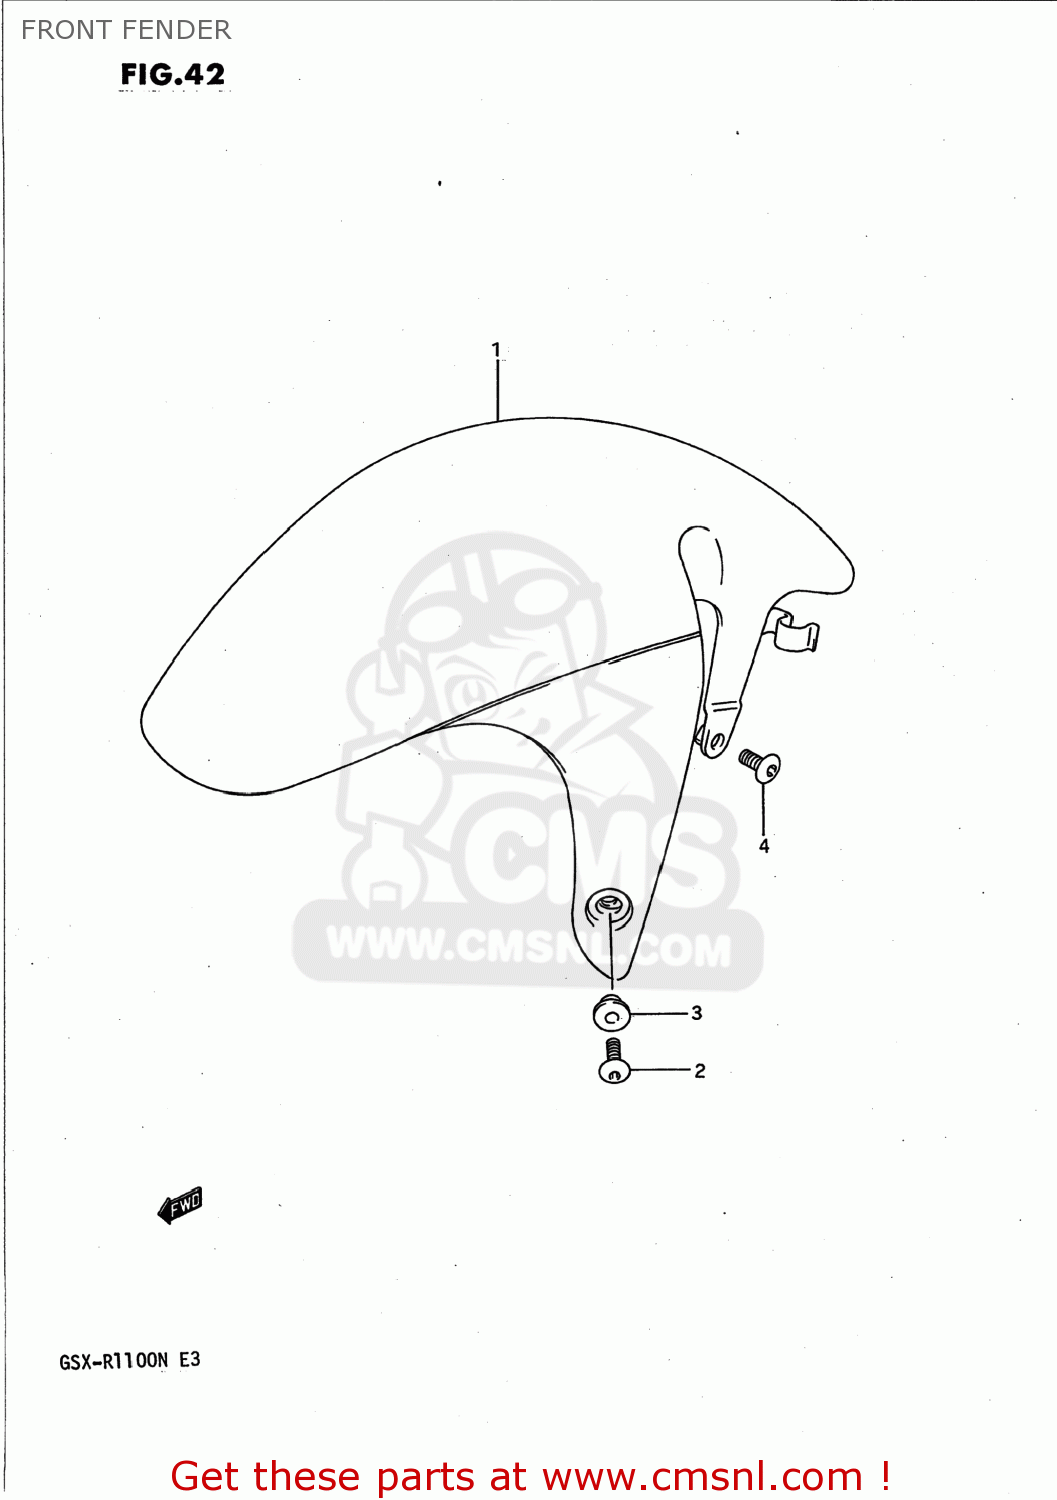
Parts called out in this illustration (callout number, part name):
1	FENDER,FRONT
2	SCREW(6X16)
3	WASHER(6.3X16X1.5)
4	SCREW(8X16)
